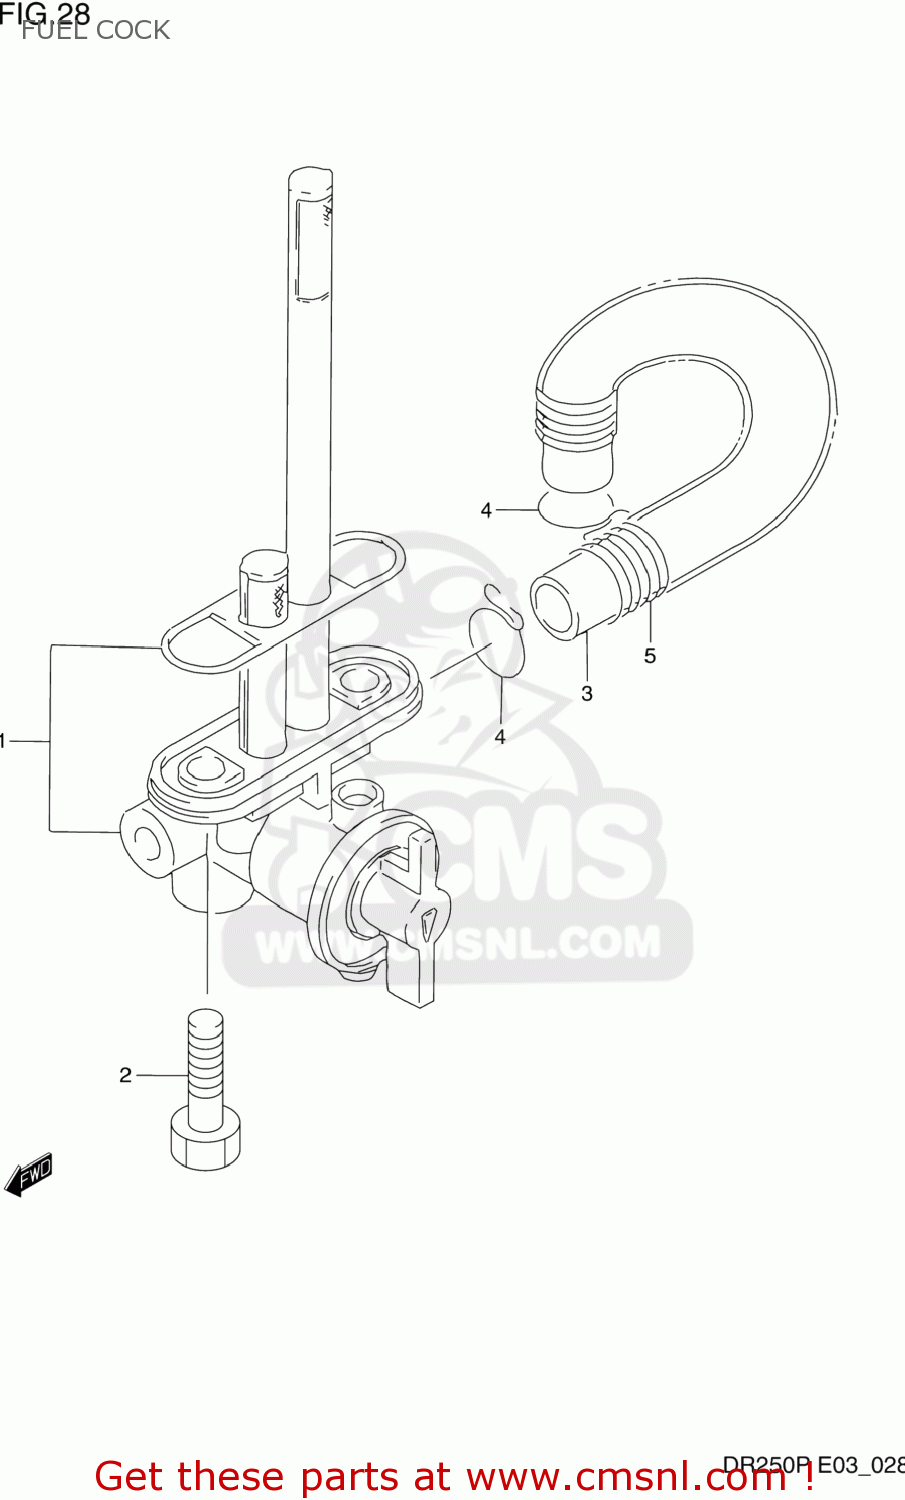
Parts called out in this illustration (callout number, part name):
1	COCK ASSY,FUEL
2	SCREW
3	HOSE
4	CLIP
5	SPRING
